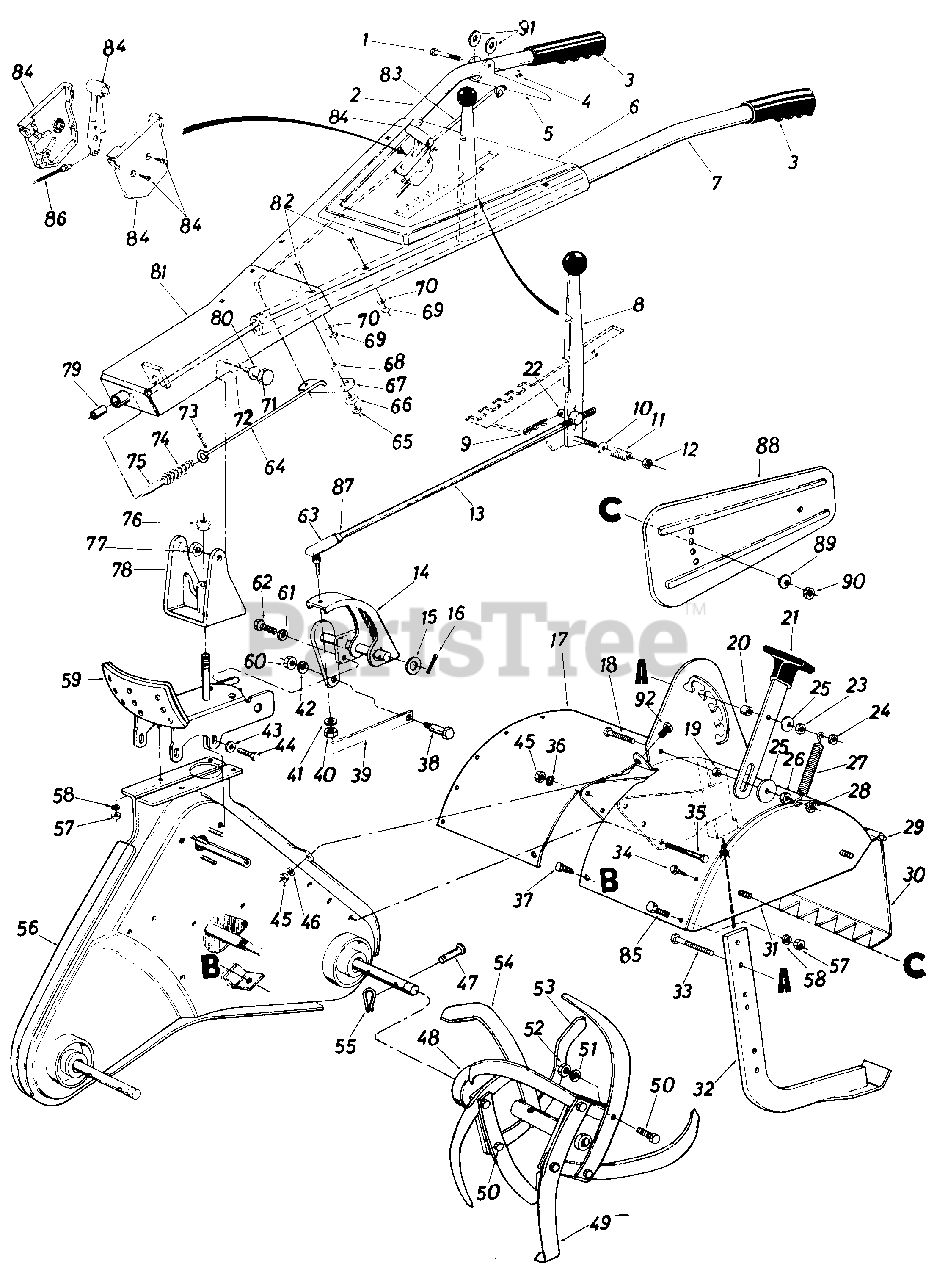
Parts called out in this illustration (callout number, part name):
1	SCREW-HEX 1/4-20 X 1.75
2	HANDLE-RH
3	GRIP-BLACK
4	NUT-HEX CENTER L-1/4-20
5	HANDLE ASSY-CLUTCH
6	PANEL-HANDLE
7	HANDLE-LH
8	HANDLE ASSY-CLUTCH
9	PIN-COTTER
10	WASHER-BELL .400 ID X .88 X .060
11	SPRING-COMPRESSION
12	NUT-HEX INS L 3/8 X 24
13	ROD-CONTROL
14	PIVOT HORN
15	WASHER-FL
16	PIN-COTTER-1/8 DIA X .75
17	SHIELD ASSY-TINE
18	SCREW-HEX 3/8-16 X 1.50
20	SPACER
21	HANDLE ASSY-DEPTH BAR
22	BUSHING-PIVOT
23	NUT-HEX 3/8-16
24	NUT-HEX INS L-3/8-16
25	WASHER-FL-.39 X 1.5
26	NUT-HEX 3/8-16
28	NUT-HEX INS L-3/8-16
30	FLAP ASSY-TINE SH HG
31	COVER-SIDE-LH
32	BAR-DRAG
33	SCREW-HEX 3/8-16 X 1.75
34	SCREW-HEX WASH HD 5/16-18
35	SCREW-HEX 3/8-24 X 3.0 LG
36	WASHER-LOCK-3/8
37	SCREW-HEX WASH SF TAPP 3/8 X 3/4
38	BOLT-SHLD
39	STRIP-CONTROL
40	NUT-HEX INS L-3/8-24
41	WASHER-LOCK-3/8
42	WASHER-LOCK-3/8
43	WASHER-BELL .400 ID X .88 X .060
44	SCREW-HEX WASH SF TAPP 3/8 X 3/4
45	NUT-HEX 3/8-24
46	WASHER-LOCK-3/8
47	PIN-CLEVIS
48	ADAPTER ASSY-TINE
49	TINE ASSY-LH-COMP
50	SCREW-TRUSS MACH SCR 10-24 X .38
51	WASHER-LOCK-3/8
52	NUT-HEX 3/8-24
55	PIN-COTTER
56	CHAIN CASE ASSY-COMP
57	NUT-HEX 5/16-18
58	WASHER-LOCK-5/16
59	HANDLE POSITIONER
60	NUT-HEX INS L-3/8-16
61	WASHER-LOCK-5/16
62	SCREW-HEX WASH SF TAPP
63	JOINT ASSY-BALL
65	NUT-HEX CENTER L-5/16-18
66	BEARING-FLANGE .360 ID
68	WASHER-BUSHING
69	NUT-HEX 5/16-18
70	WASHER-LOCK-5/16
71	SCREW-SHLD .498 DIA X .340
72	WASHER-BELL .505 ID X 1.00 OD
73	PIN-COTTER-1/8 DIA X .75
75	PIN-LOCKING
76	NUT-HEX INS L-5/8-18
77	NUT-HEX TOP LOCK-3/8-16
78	BRACKET-PIVOT
79	BEARING-SLEEVE .505 ID
80	WASHER-FL-.531 ID X .93 OD X .090
81	BRACKET-MTG
82	BOLT-CARRIAGE 5/16-18 X 1.75
84	CONTROL-THROTTLE
85	SCREW-HEX 5/16-18 X .75
86	WIRE-CONTROL
87	NUT-HEX JAM 3/8X24
90	NUT-HEX 5/16-18
91	WASHER-FL-.28 ID X .74 OD X .063
92	SCREW 3/8-24X1.25 GR5
15390-0637	SHIELD-SIDE (POWDER BLACK) - POWDER BLACK (0637)
